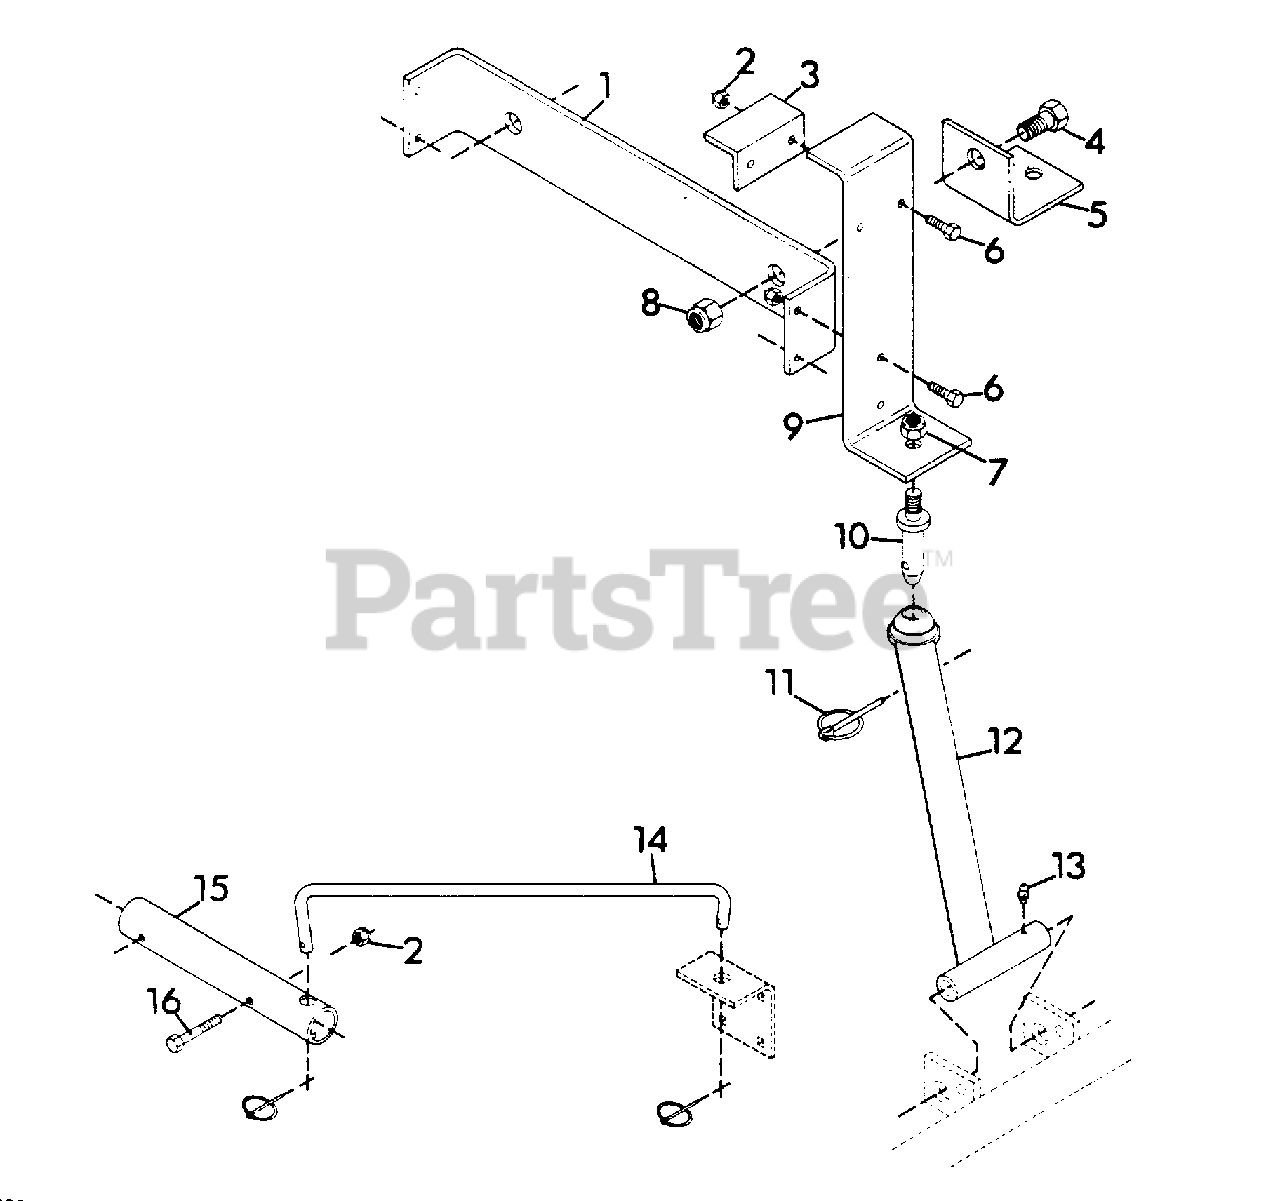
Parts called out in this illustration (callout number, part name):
1	BRACE, REAR HITCH
2	NUT, LOCK 3/8-16
3	BRACKET, MOUNTING
4	BOLT, HEX 3/4-10X1.50
5	BRACKET, TOWING
6	BOLT, HEX 3/8-16X1.25
7	NUT, LOCK 5/8-11
8	NUT, LOCK 3/4-10
9	BRACKET, REAR HITCH MOUNTING
10	PIN, REAR HITCH
11	PIN, LYNCH
12	WELDMENT, REAR HITCH
13	FITTING, LUBE 1/4-28
14	ROD, STABILIZER
15	TUBE, STABILIZER ROD MOUNTING
16	BOLT, HEX 3/8-16X2.50
